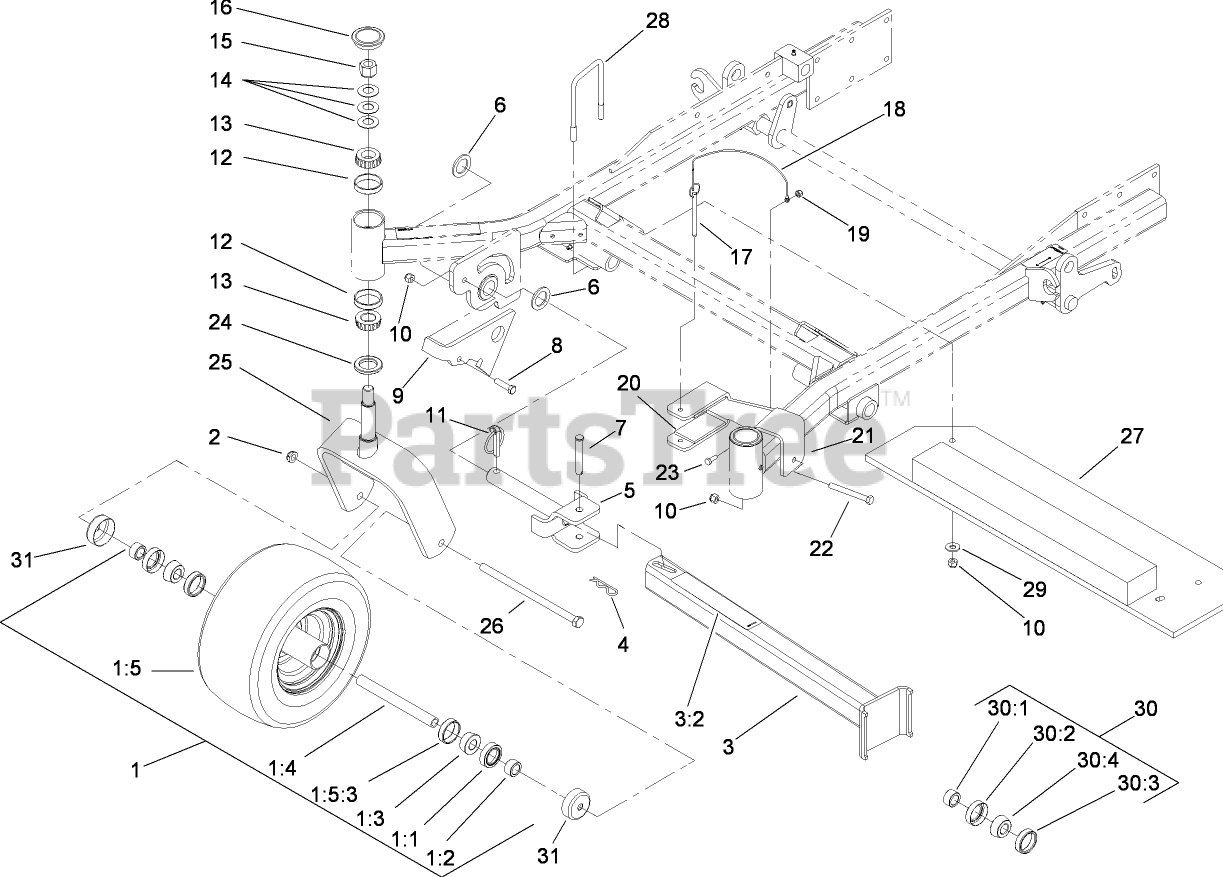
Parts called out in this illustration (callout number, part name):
1	CASTOR WHEEL ASM (SEMI-PNEUMATIC)
1:1	SEAL-BEARING
1:2	SPACER-BEARING
1:3	BEARING-CONE, TAPER
1:4	SPACER-CASTER, FRONT
1:5	WHEEL AND TIRE ASM (SEMI-PNEUMATIC)
1:5:3	BEARING-CUP
2	NUT-LOCK, NI
3	Leg ASM
3:2	DECAL-Z STAND
4	PIN-HAIR
5	PIN-PIVOT
6	WASHER-THRUST
7	PIN-CLEVIS
8	SCREW-HH
9	BRACKET-LATCH
10	NUT-LOCK, NI
11	PIN-LYNCH
12	BEARING-CUP, TAPERED
13	BEARING-CONE, TAPERED
14	WASHER-BELLVILLE
15	NUT-LOCK, NI
16	CAP-GREASE
17	PIN-HITCH, COTTERLESS
18	LANYARD-NYLON
19	NUT-LOCK, NI
20	Cushion-Rubber
21	BRACKET-CRADLE
22	SCREW-HH
23	SCREW-HH
24	SEAL-GREASE
25	CASTER
26	SCREW-HH
28	U-BOLT, 3IN
29	WASHER-FLAT
30	CASTER WHEEL BEARING KIT
30:1	SPACER-BEARING
30:2	SEAL-BEARING
30:3	BEARING-CUP
30:4	BEARING-CONE, TAPER
31	GUARD-SEAL
